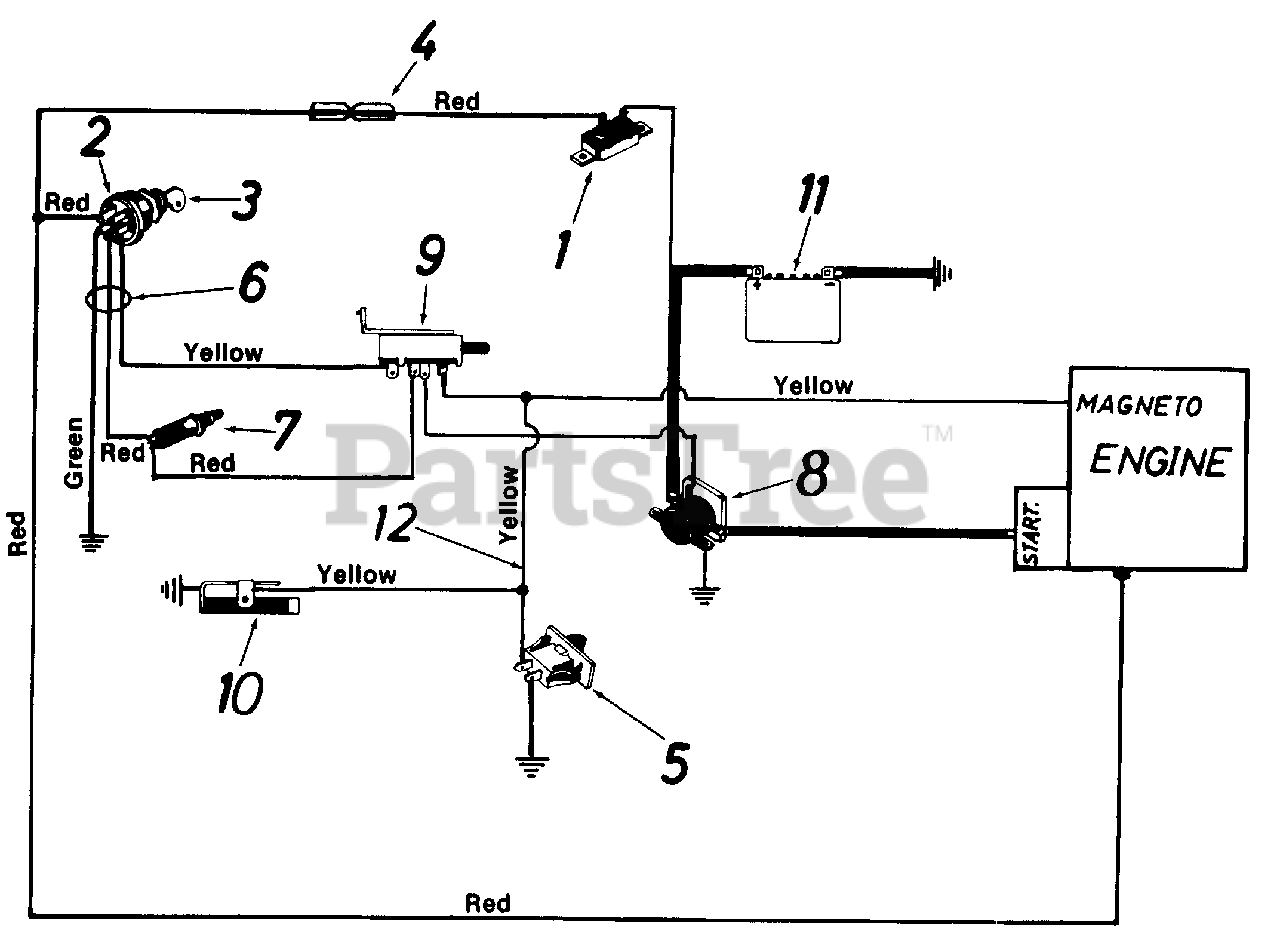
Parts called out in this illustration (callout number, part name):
1	Circuit Breaker
2	Ignition Switch
3	Ignition Key
4	Insulated Tab Adapter
5	Safety Switch
6	Wire Harness
7	Safety Switch
8	Solenoid
9	Safety Switch
10	Spring Switch
11	12-V Battery
12	Wire Lead
